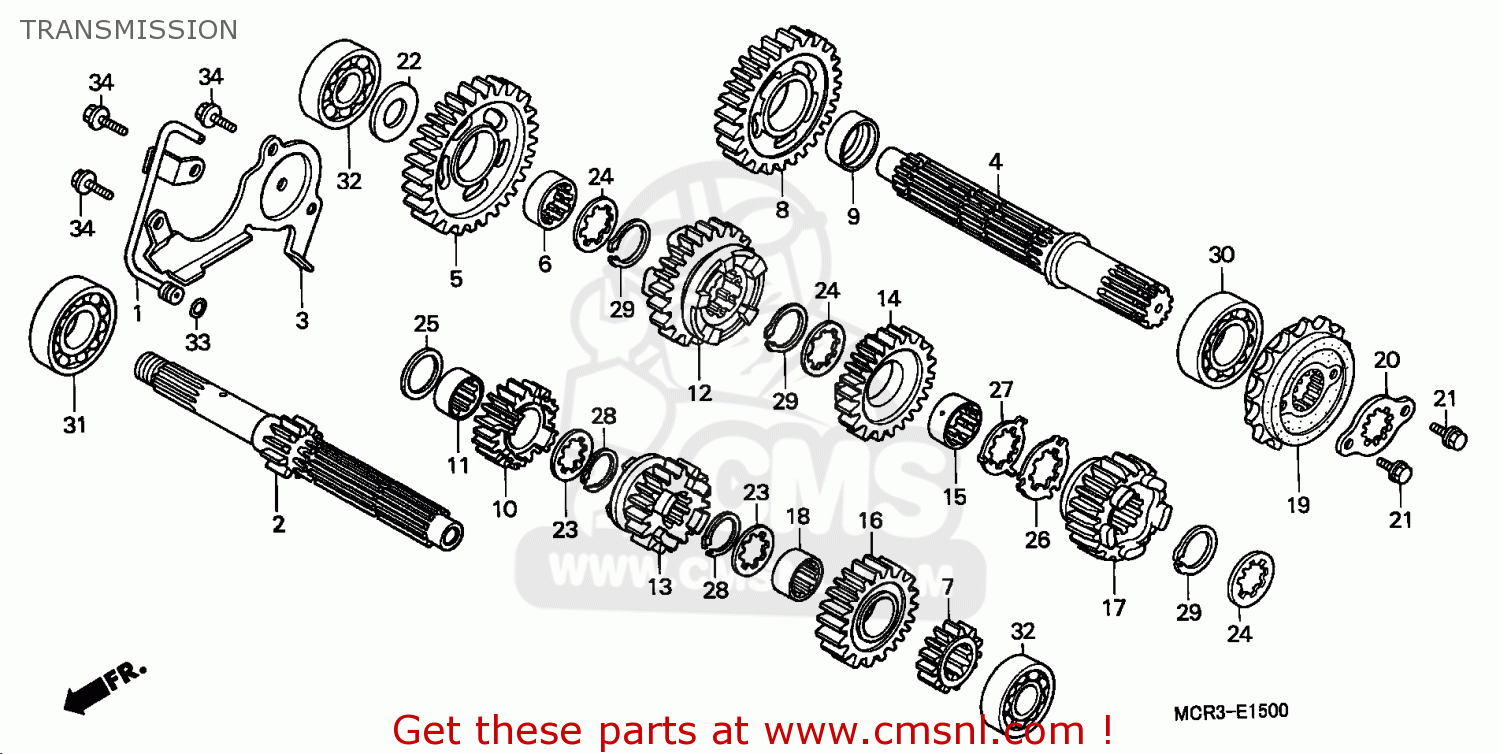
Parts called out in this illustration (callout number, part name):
1	PIPE COMP,TRNS.FE
2	SHAFT COMP,MAIN
3	PLATE,BEARING SET
4	SHAFT,COUNTER
5	GEAR,C-1
6	COLLAR,SPLINE 28X
7	GEAR,M-2
8	GEAR,C-2
9	BUSH,28X31X10
10	GEAR,MAINSHAFT TH
11	BUSH,25X28X13.5
12	GEAR,C-3
13	GEAR,M-4
14	GEAR,C-4
15	COLLAR,SPLINE 28X
16	GEAR,M-5
17	GEAR,C-5
18	COLLAR,SPLINE 25X
19	SPROCKET,DRIVE 17
20	PLATE,FIXING
21	BOLT,FLANGE,6X12
22	WASHER,20X37X2
23	WASHER,SPLINE,25X
24	WASHER SPLINE 28X
25	WASHER,25MM
26	WASHER,SPLINE 28M
27	WASHER LOCK,28MM
28	CIR CLIP,25MM
29	CIRCLIP,28MM
30	B/BRG N/RAD N/COM
31	BEARING,BALL RADI
32	BRG.,BALL RADIAL
33	O-RING,5.6X1.9
34	BOLT,FLANG,6X16
